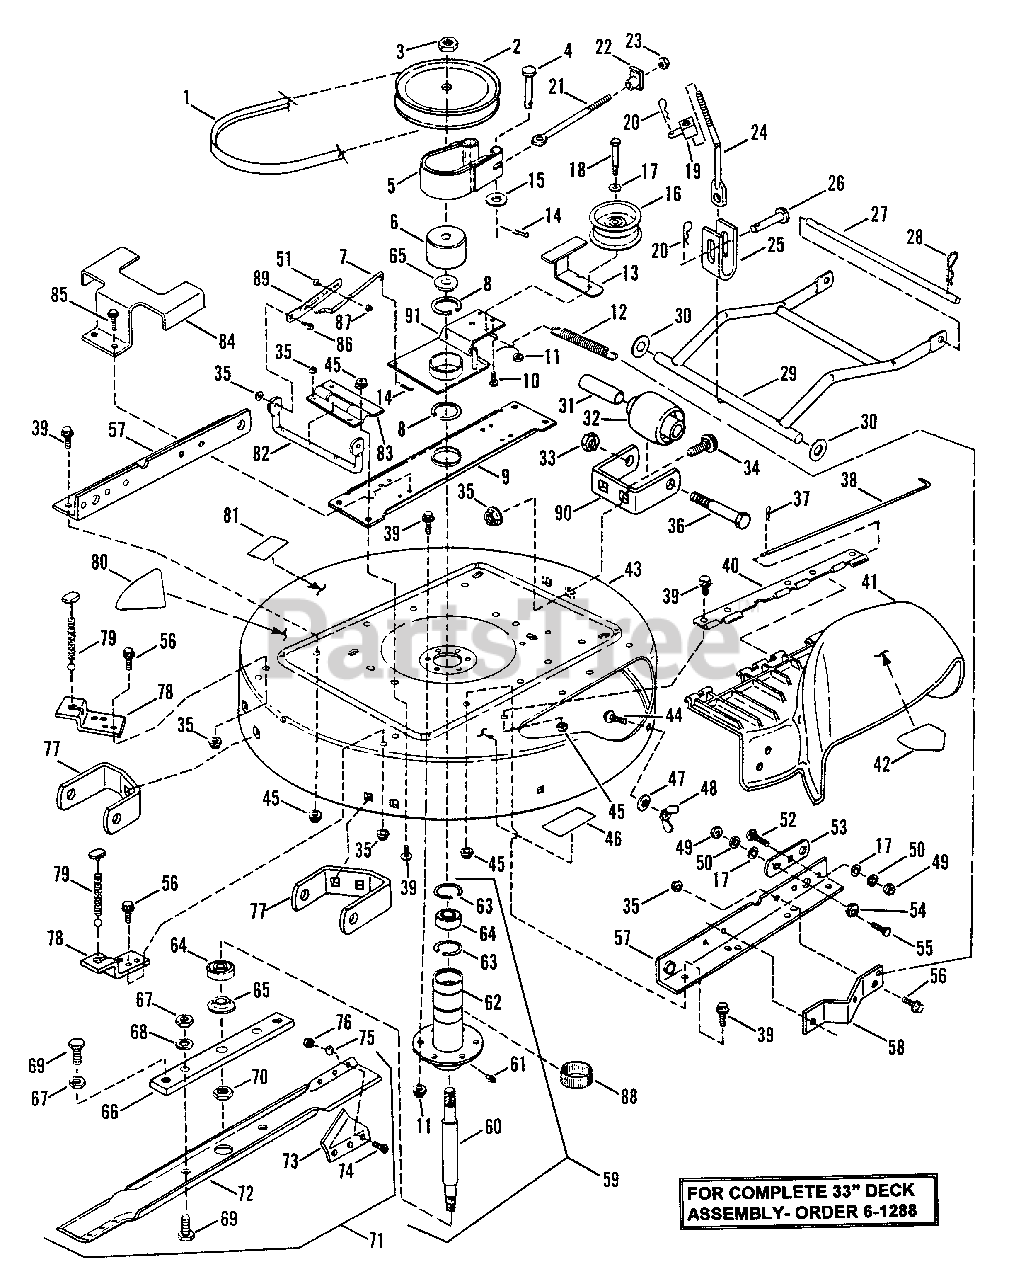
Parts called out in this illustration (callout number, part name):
1	BELT, 33" Drive
2	PULLEY, Spindle, 7" O.D.
3	NUT, 3/4-16 Hex Jam
4	PIN, 1/4 x 1 1/4" Clevis
5	BAND, Brake
6	DRUM, Brake
7	ROD, Link, Clutch/Brake
8	RING, 2" External Retaining
9	BRACE, Spindle
10	SCREW, 5/16-18 x 3/4" Self-Tapping
11	NUT, 3/8-16 Hex Cntr. Lock
12	SPRING, Clutch & Brake
13	GUIDE, Belt
14	COTTER-PIN, 3/32 x 3/4"
15	WASHER, Flat
16	PULLEY, Idler 3 1/4" O.D.
17	WASHER, 3/8 SAE
18	BOLT, 3/8-16 x 1 3/4" Hex Hd.
19	SWIVEL, Brake
20	PIN, 1/4 x 1 1/8" Hair
21	BOLT, 1/4-20 Eye
22	NUT, 1/4-20 Tee
23	NUT, 1/4-20 Hex
24	ROD, Front Lift
25	BRACKET, Front Lift Hanger
26	PIN, 3/8 x 1 1/2" Clevis
27	PIN, Front Deck Hanger
28	PIN, .148 x 2.62" Hair
29	LIFT, Front Arm
30	WASHER, Flat
31	SPACER
32	WHEEL, Gage
33	NUT, 3/8-24 Hex Lock
34	BOLT, 5/16-18 x 1/2" Short Neck Carriage
35	NUT, 5/16-18 Hex Flange Lock
36	SCREW, 3/8-24 x 3 3/4" Hex Head Cap
37	PIN, Hair
38	PIN, Hinge
39	BOLT, 3/8-16 x 3/4" Hex Flange Lock
40	HINGE, Deflector
41	ASSEMBLY, Deflector
42	DECAL, Danger (Cut Finger)
43	DECK, Cutting, 33"
44	BOLT, 5/16-18 x 3/4" Short Neck Carriage
45	NUT, 3/8-16 Hex Flng. Lk.
46	DECAL - CAUTION (Deflector)
47	WASHER, 5/16 Flat
48	WING-NUT. 5/16-18
49	NUT, 3/8-16 Hex
50	WASHER, 3/8 Split Lock
51	BOLT, 1/4-20x1/2" Hex Flange Lock
52	BOLT, 3/8-16 x 3/4" Carriage
53	LINK, Adjustment
54	ECCENTRIC, Leveling
55	SCREW, 3/8-16 x 1" Hex Head Cap
56	BOLT, 5/16-18 x 1/2" Hex Flange Lock
57	RAIL, Side
58	ANCHOR, Brake
59	ASSEMBLY, Spindle
60	SPINDLE
61	FITTING, Lube (Press fit for .187 hole-no ball)
62	HOUSING, Spindle
63	RING, Retaining
64	BEARING, Spindle
65	WASHER, Spindle
66	HOLDER, Blade
67	NUT, 1/2-20 Hex Jam (2 in assembly)
68	WASHER, 1/2 Int. Tooth Lk.
69	SCREW, 1/2-20 Hex Head Cap (2 in assembly)
70	NUT, 5/8-18 Hex Lock
71	ASSEMBLY, Blade & Air Lift
72	BLADE, 33" Mower Deck
73	AIR-LIFT
74	SCREW,5/16-24 x 11/16" Machine
75	WASHER, 5/16 Internal Tooth Lock
76	NUT, 5/16-24 Hex
77	BRACKET, Gage Wheel Rear
78	BRACKET, Rear Lift
79	CABLE, Deck Lift, Rear
80	DECAL, 33" Hi-Vac
81	DECAL - CAUTION (Rotating Blades)
82	ARM, Pivot
83	BRACKET, Pivot Arm
84	GUIDE, Belt
85	SCREW, 5/16-18 x 5/8" Self- Tapping
86	SCREW, 5/16-18 x 3/4" Shoulder
87	NUT, 1/4-20 Hex Flange Lock
88	RING, Tolerance
89	BRACKET, Link, Clutch/Brake
90	BRACKET, Gage Wheel (Front)
91	ARM, Idler
